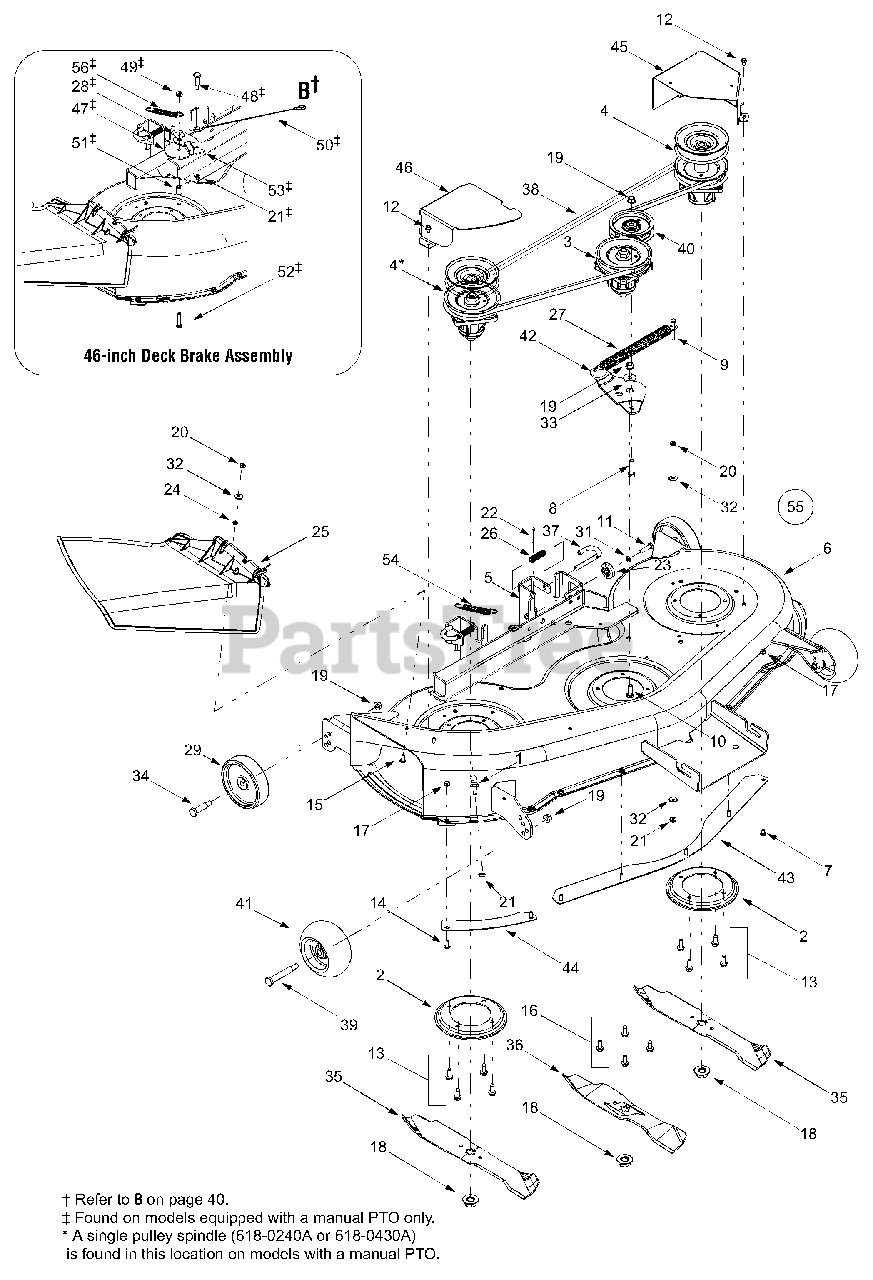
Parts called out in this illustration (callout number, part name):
1	Grass Catcher Pin
4	Double Pulley Spindle Assembly
8	Hex Cap Screw, 3/8-16 x 1.5
9	Hex Cap Screw, 1/4-20 x 2.0
10	Hex Cap Screw, 3/8-16 x 1.0
11	Hex Cap Screw, 5/8-18 x 1.25
12	Self-tapping Screw,1/4-20 x.5
13	Self-tapping Screw,15/16-18 x.875
14	Hex Screw, 1/4-20 x.75
15	Hex Cap Screw, 1/4-20 x.62
16	Self-tapping Screw, 5/16-18 x.75
17	Hex Sems Nut, 1/4-20
18	Hex Flange Nut, 5/8-18
19	Flange Lock Nut, 3/8-16
20	Hex Nut, 1/4-20
21	Hex Flange Lock Nut, 1/4-20
22	Cotter Pin, 1/8 x 1.25
23	Deck Adjustment Gear
24	Push Nut.25 x.5
25	Side Discharge Chute Assembly
26	Compression Spring,.406 x.531 x 1.75
27	Extension Spring,.91 x 7.3
28	Shoulder Spacer
29	Deck Wheel, 5 x 1.38
31	Lock Washer, 5/16
32	Bell Washer,.265 x.75 x.062
33	Shoulder Spacer,.625 x 1.16
34	Shoulder Screw
35	Three-in-one Blade, Star Center, 16.28"
36	Three-in-one Blade, Star Center, 14.88"
37	Deck Release Pin
38	Deck Belt, Poly
39	Shoulder Screw, 1/2-2.5
40	Idler Pulley, 3.5
41	Deck Wheel, 5.0
48	Shoulder Screw,.374 x 1.16
49	Hex Nut, 5/16-18
50	Bracket Cable, 12"
51	Spacer,.385 x.625 x.70
52	Hex Cap Screw, 5/16-18 x 1.5
53	Deck Brake Assembly
54	Deck Lift Extension Spring, 1.15 x 5.99
